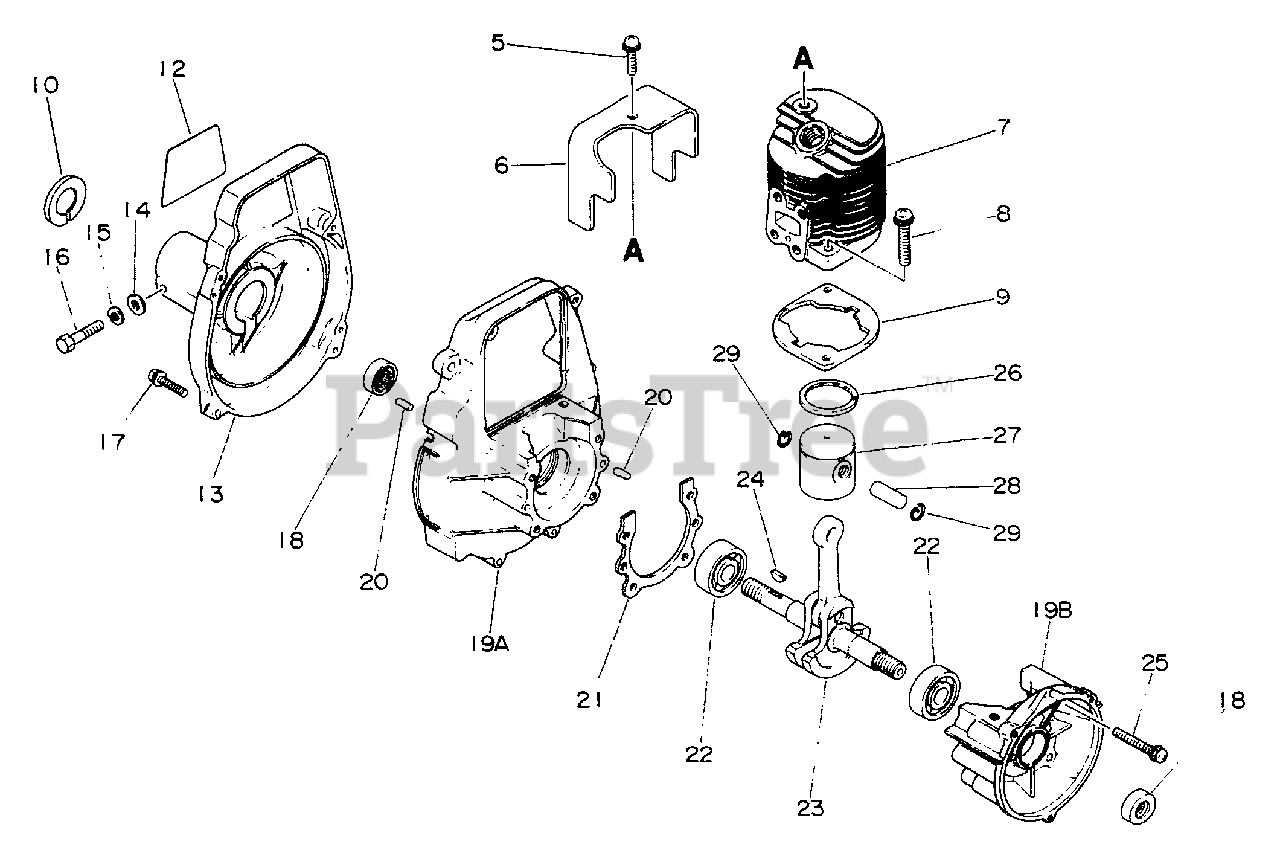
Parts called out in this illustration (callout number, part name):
5	SCREW 5×10
6	COVER, CYLINDER
7	CYLINDER
8	SCREW 6×20
9	GASKET, CYLINDER
10	SPACER
12	LABEL
13	CASE, FAN
14	WASHER, FLAT 5.5×10×0.8
15	WASHER, SPRING 5
16	BOLT - 5×20
17	SCREW 4×20
18	SEAL, OIL
19	CRANKCASE KIT
19A	CRANKCASE KIT
19B	CRANKCASE KIT
20	PIN, LOCATING 4
21	GASKET, CRANKCASE
22	BEARING, BALL 6200
23	CRANKSHAFT
25	SCREW 5×30
26	RING, PISTON
27	PISTON
28	PIN, PISTON
29	RING, SNAP
